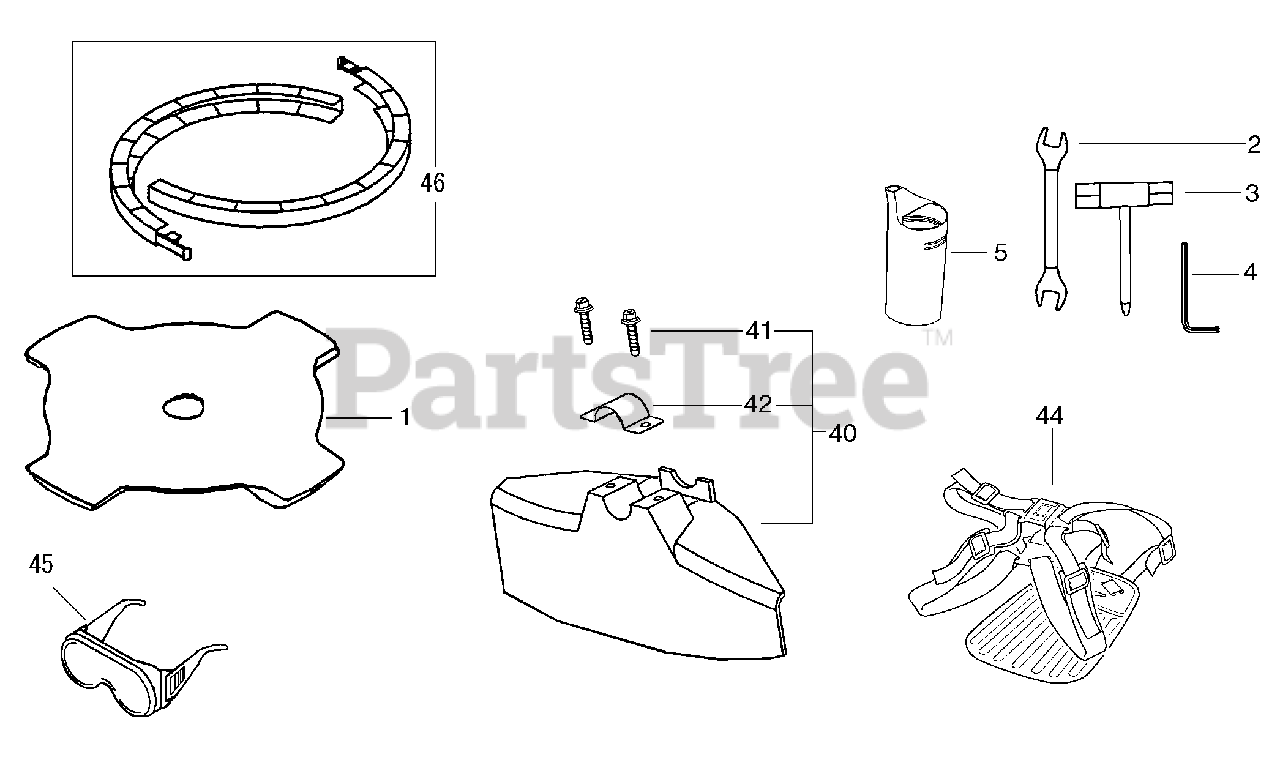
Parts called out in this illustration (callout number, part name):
1	BLADE, BRUSHCUTTER
2	SPANNER - 8X10mm
3	T-WRENCH - 17X19mm
4	HEX KEY - 5mm
5	MIXER, FUEL
40	DEBRIS SHIELD ASSY
41	BOLT - 6X28
44	HARNESS ASSY
45	GOGGLES
46	COVER, BLADE
